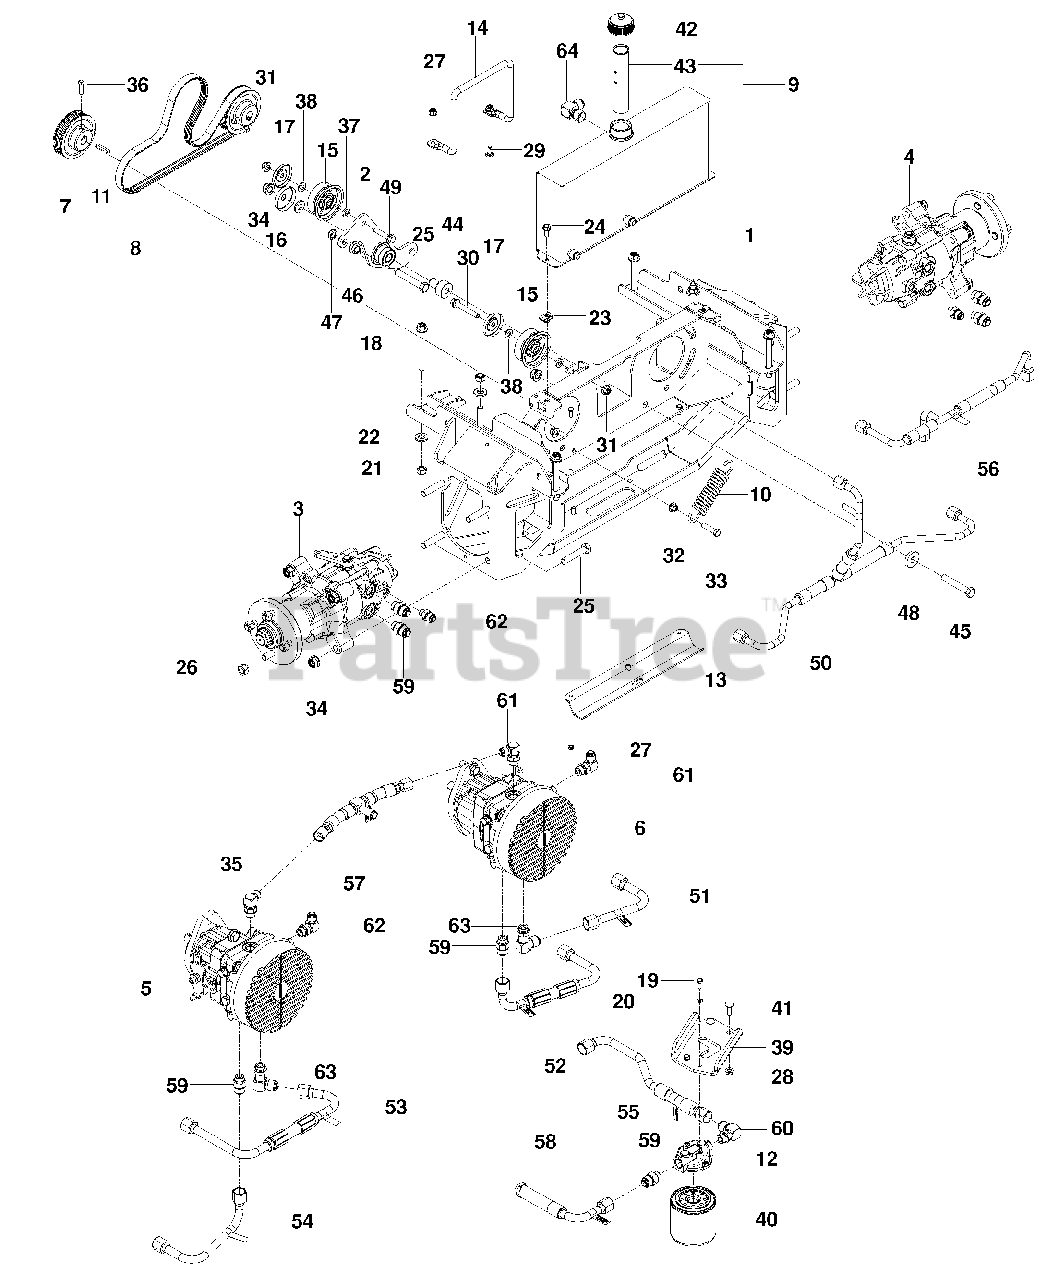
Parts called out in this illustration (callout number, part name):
1	PUMP BAY, BLK
2	IDLER w/ BEARINGS ASSY
3	MOTOR, PRM, RT
4	MOTOR, PRM, LT
5	PUMP, 21CC, RT
6	PUMP, 21CC, LT
7	SHEAVE, PUMP
8	BELT, PUMP
9	RESERVOIR ASSY
11	KEY, 5MM SQ x 36MM
12	HEAD, FILTER
13	GUARD, HOSE
14	GUIDE, BELT
15	PULLEY, IDLER
16	SHIELD, DUST 1/2 ID
17	SHIELD, DUST
18	BOLT 7/16-14 x 4 GR8 BLK
19	HCS 1/4-20 x 5/8
20	WASHER 1/4 SPLT LK
21	NUT 7/16-14 HEX NYLOC
22	WASHER, SAE
23	RETAINER, U TYPE
24	HHFS 5/16-18 x 3/4
25	HCS 1/2-13 x 2 1/2
26	NUT 1/2 LUG
27	NUT 1/4-20 HEX THIN NYLOC
28	NUT 5/16-18 HEX FLANGE NYLOC
29	RHSNB 5/16-18 x 3/4
30	HHFS 3/8-16 x 2 1/2
31	NUT 3/8-16 HEX FLG NYLOC
32	NUT 3/8-16 HEX WHIZLK
33	HCS 3/8-16 x 1 1/2 GR 8
34	NUT 1/2-13 HEX FLG NYLOC
35	BOLT 1/2-13 x 1 1/4 WHIZLK SP
36	SCREW 3/8-16 x 1 1/2 HEX HD
37	WASHER 3/8 x 3/4
38	WASHER 3/8 SAE FLT
39	MOUNT, FILTER, BLK
40	FILTER, 25 MICRON
41	BOLT 5/16-18 x 1 RD HD
42	CAP, RESERVOIR
43	TUBE, ANTI-SPLASH
44	PIVOT, BEARING
45	HCS 1/2-13 x 3
46	NUT 1/2-13 HEX WHIZLK
47	1/2-13 HEX NUT THIN NYLOC
48	WASHER, 1/2 x 1/2
49	BOLT 3/8-16 x 1 3/4 WHIZLK
50	LINE, HYD, CASE-PRM
51	LINE, HYD, LT-AA
52	LINE, HYD, LT-BB
53	LINE, HYD, RT-AB
54	LINE, HYD, RT-BA
55	LINE, HYD, SUCTION
56	LINE, HYD, CASE-PUMP
57	LINE, HYD, CHARGE
58	LINE, HYD, CHARGE
59	FITTING, 10-8 STRAIGHT
61	ELBOW 90O ADJ
62	FITTING, HYD
63	FITTING, 10-8 90O
64	FITTING, HYD, 6500-10-8
